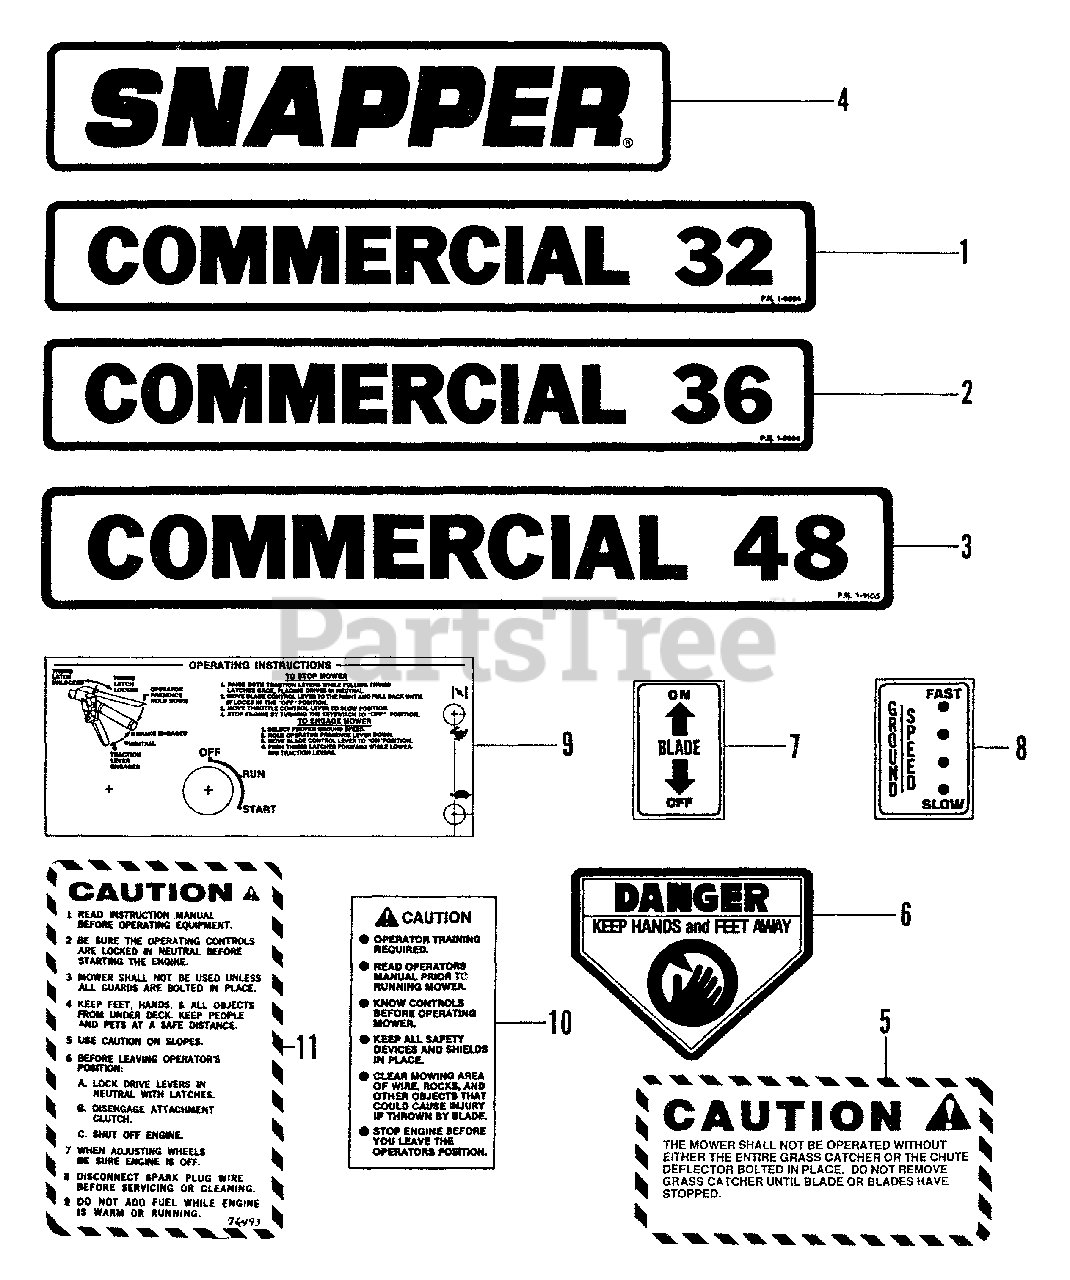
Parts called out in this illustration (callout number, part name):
1	DECAL, 32 Commercial
2	DECAL, 36 Commercial
3	DECAL, 48 Commercial
4	DECAL, Snapper
5	DECAL, Caution
6	DECAL, CPSC Caution
7	DECAL, Blade
8	DECAL, Ground Speed
9	DECAL, Control Panel
10	DECAL, Caution
11	DECAL, Caution
